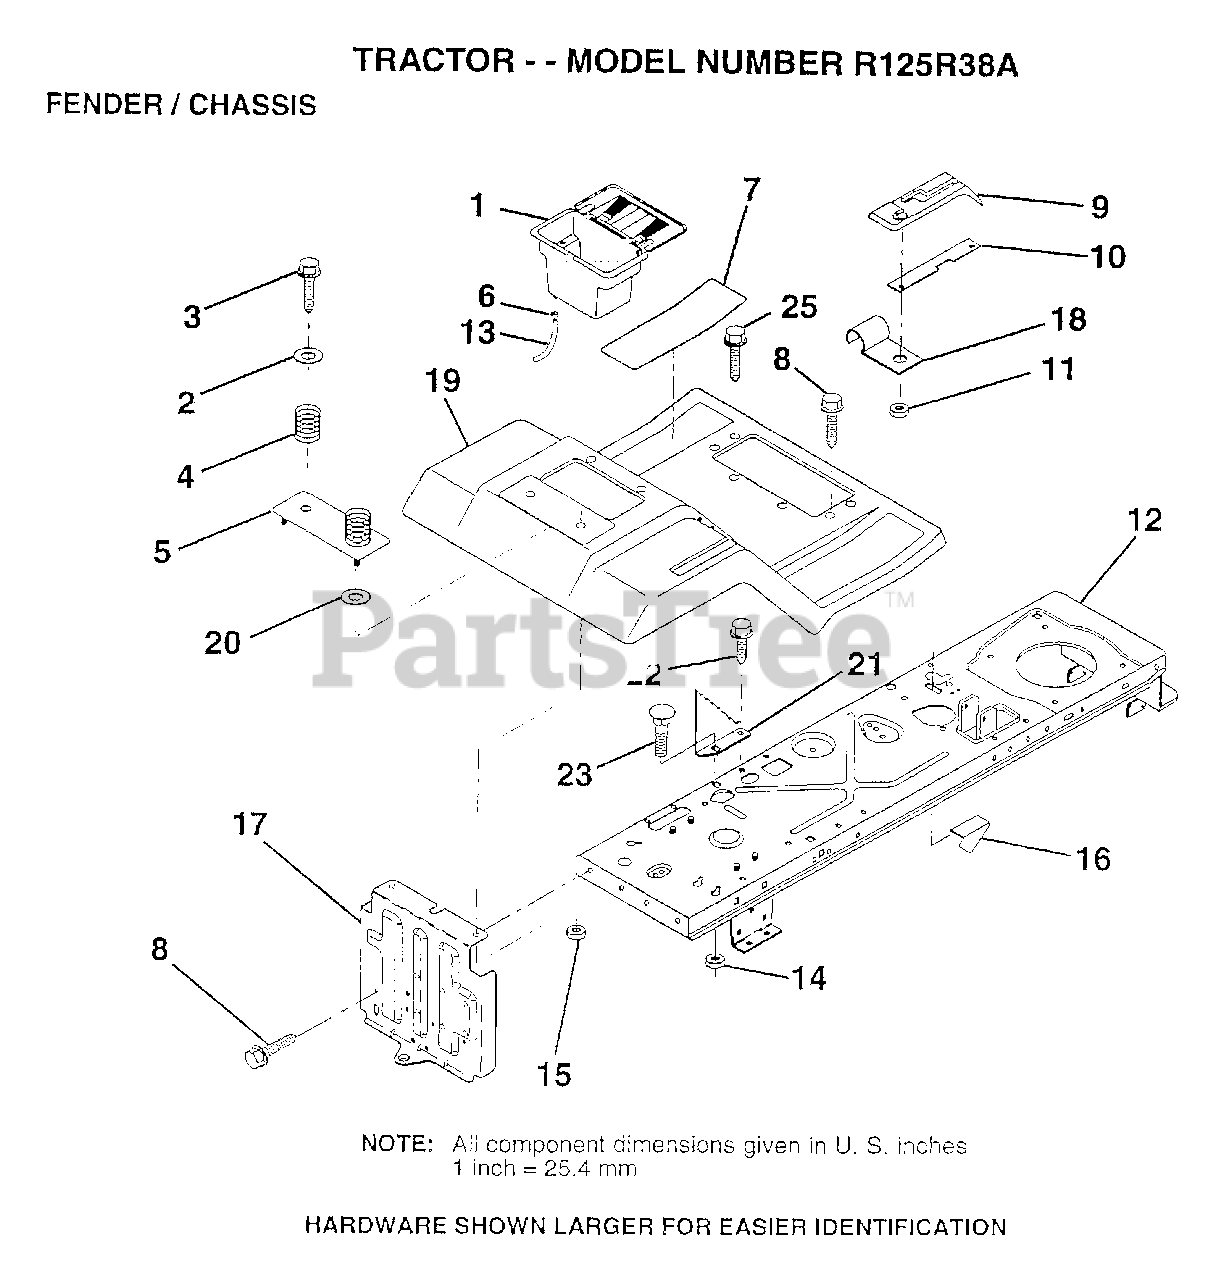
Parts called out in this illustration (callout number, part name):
2	WASHER
3	SCREW
4	SPRING, COMPRESSION, SEAT
5	BTRY FENDER PLATE
6	HOSE CLAMP T
7	PAD FOOTREST
8	SCREW
10	PLATE LOCK SHIFT
11	NUT
12	CHASSIS.WELD.ASM.
13	TUBE, BATTERY DRAIN
15	NUT HXKEP 1/4X20
17	DRAWBAR ASM LR
18	"CLIP,INSULATOR"
19	FENDER/FOOT MS505
21	BRACKET STOP DEPT
22	SCREW LT
25	SCREW
